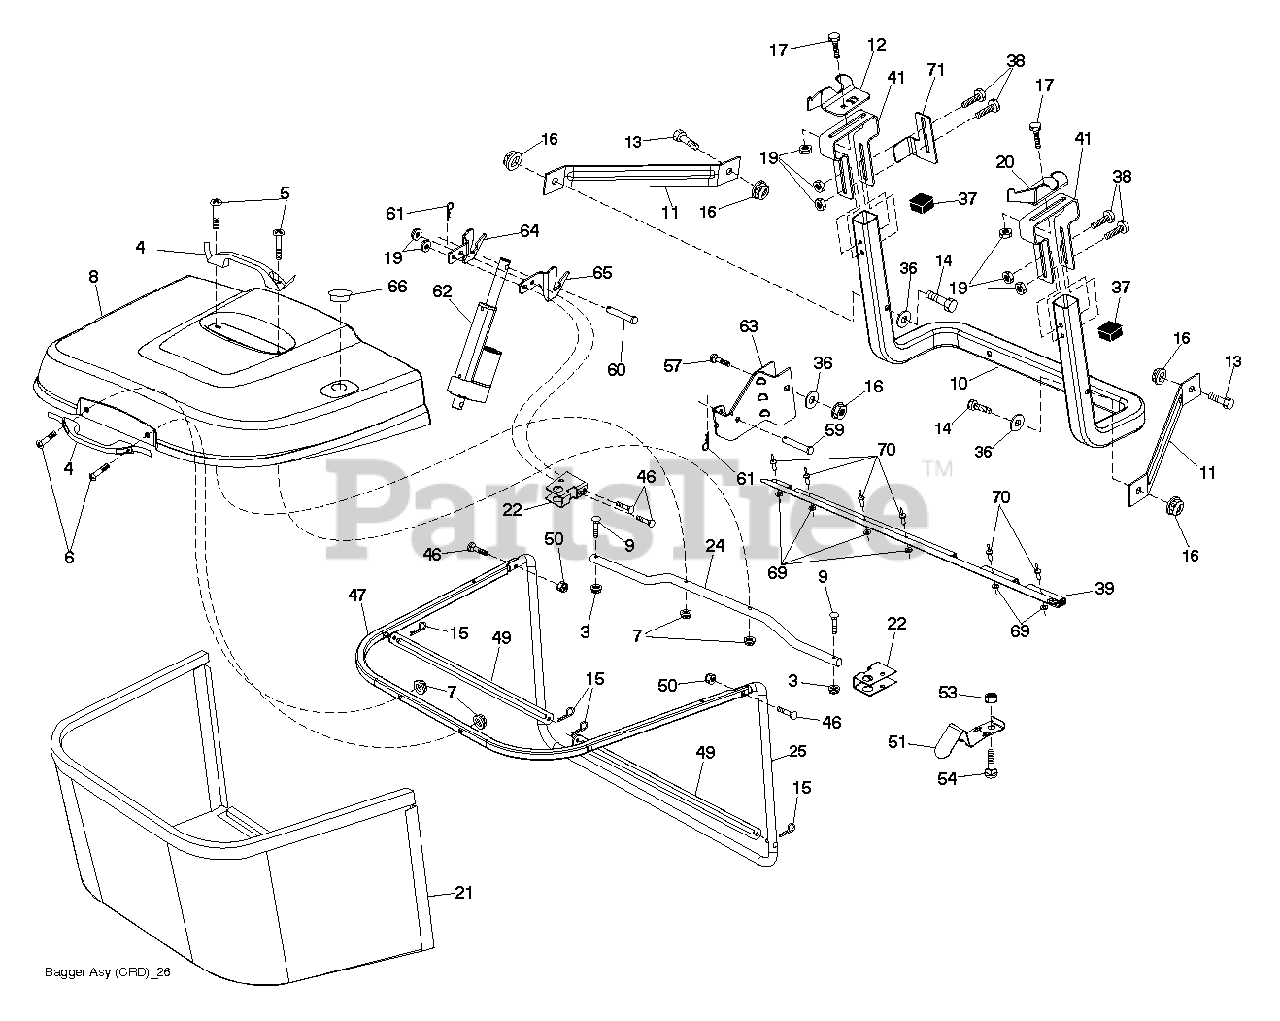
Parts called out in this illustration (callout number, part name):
3	NUT T
4	HANDLE.BAGGER.W/LVRS.BLK.CRD
5	SCREW.PAN.HEAD
6	REPL BY 532 75 00-29
8	COVER.BGR.CRD.WSLOTS.M
10	TUBE
11	BRACKET.SUPPORT.UPPER.BAG.CRD
12	BRKT PIVOT
14	BOLT-HEX EAK
15	Retainer Spring
16	NUT LOCK FLG 3/8-16 UNC
17	BOLT 5/16-18 X3/4 ZN/YEL GR 5
19	NUT LOCK HEX FLANGE 5/16-18
20	BRKT.PIVOT.RH.CRD
22	BRACKET.BAGGER.SD.ELECTRIC.CRD
24	TUBE.PIVOT.BAG.CRD.BLACK
25	PIPE
36	WASHER
37	Plug Support Bagger CRD
38	BOLT.5/16-18X2.5
39	SEAL.BAGGER.CRD
41	BRACKET.BAGGER.SD.ELECTRIC.CRD
46	BOLT.CARRIAGE.5/16-18
47	PIPE
49	ROD
50	NUT.71038.31-18.HEX.NYLOCK
51	LATCH
53	NUT
54	BOLT
57	BOLT
60	RIVET,DRILLED
61	RETAINER M
69	WASHER
70	RIVET RIVET POP
